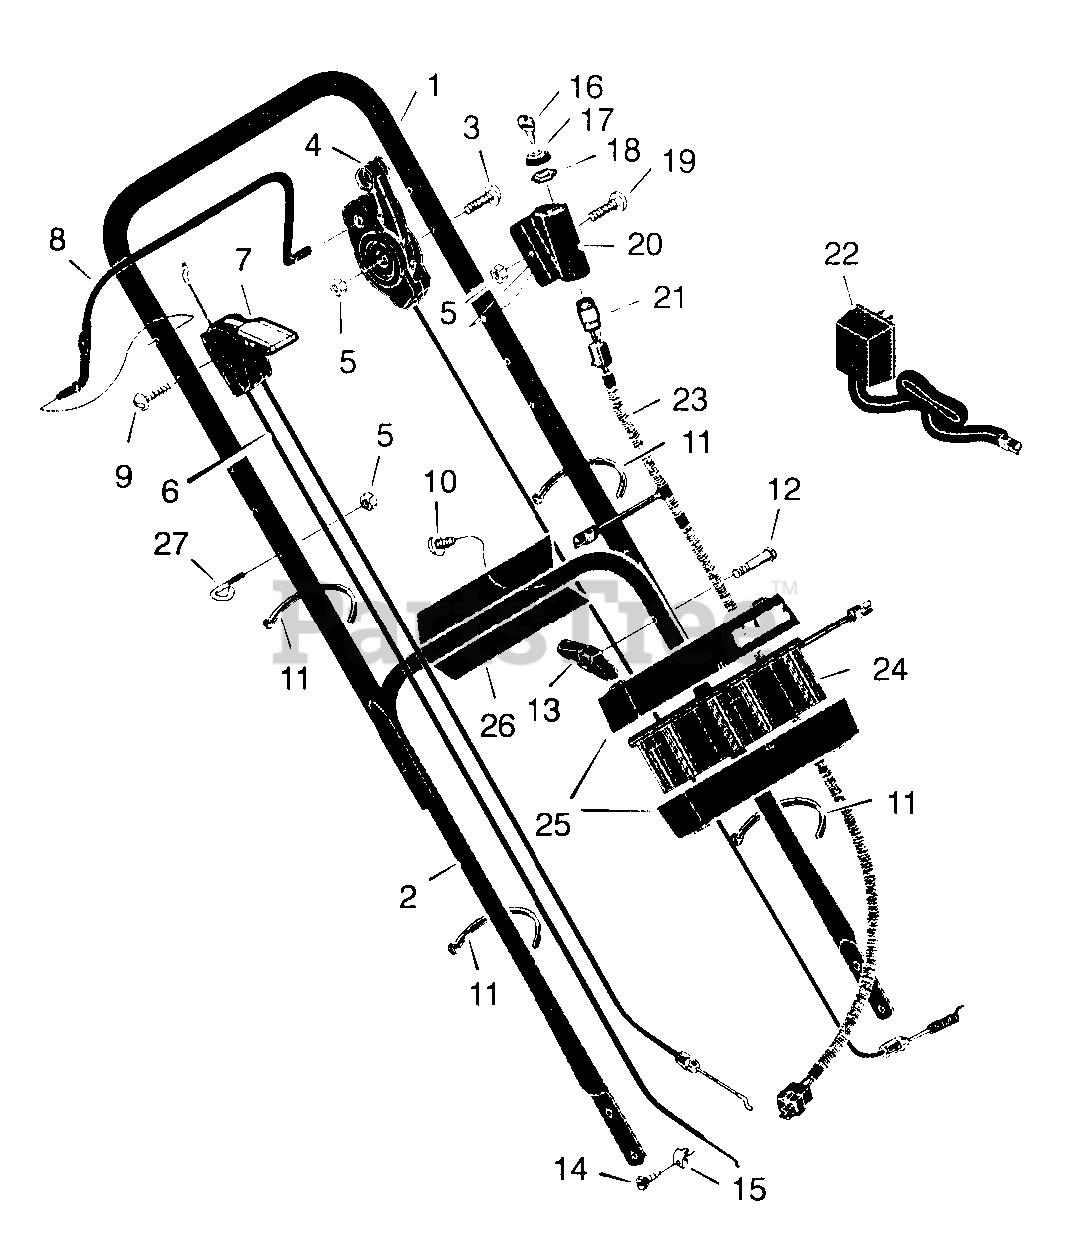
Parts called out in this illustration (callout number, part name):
1	Handle, Upper (Black)
2	Handle, Lower (Black)
4	Control, Drive
5	Locknut
6	Cable, Stop
7	Throttle Control
8	Lever, Stop
11	Fastener, Cable
13	Knob
16	Key, Ignition
17	Cap
18	Nut
20	Cover, Ignition
21	Switch Ignition & Key
22	Charger, Battery
23	Harness, Wiring
24	Battery
25	Case, Battery
26	Bracket, Battery
27	GUIDE, ROPE
